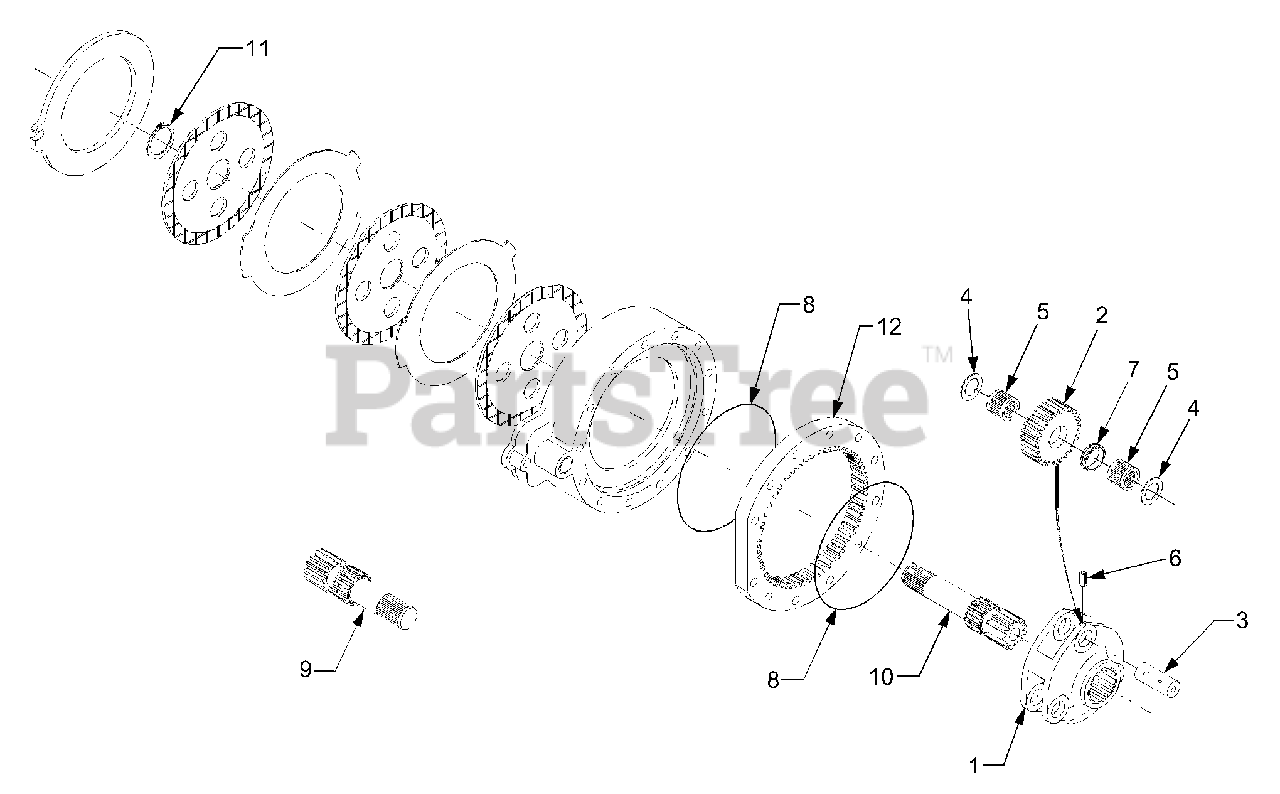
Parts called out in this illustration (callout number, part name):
1	Support, Planetary Gear
2	Gear, 27 Planetary
3	Shaft, Planetary Gear
4	Collar, Thrust
5	Bearing, Needle
9	Shaft, 13 Gear (RH)
10	Shaft, 13 Gear (LH)
12	Gear, 68 Internal
